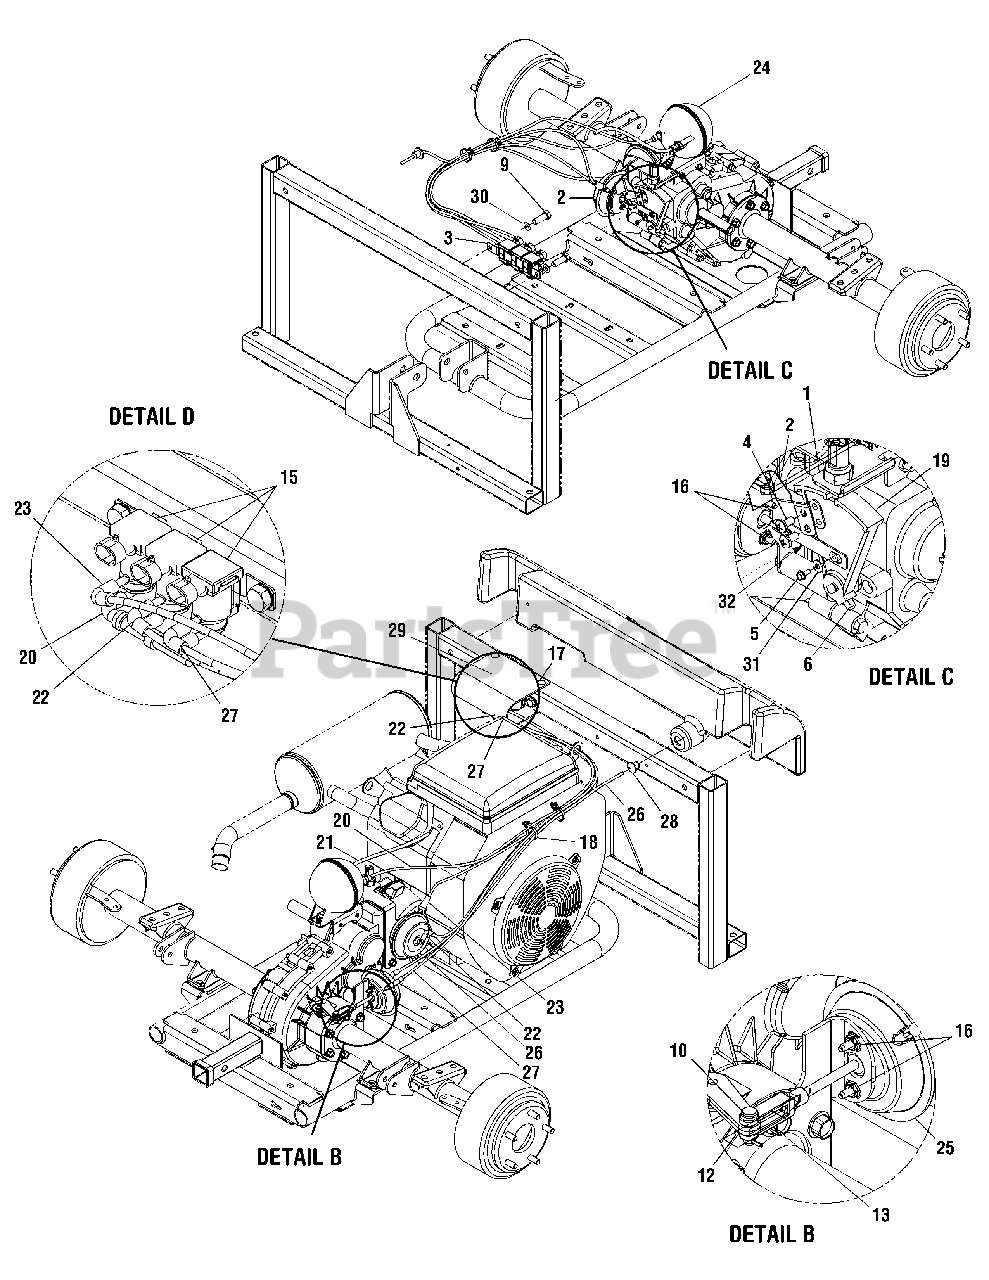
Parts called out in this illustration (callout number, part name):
1	Mounting Bracket, Vacuum Actuator
2	Bracket, Shift
3	Bracket, Vac Relay
4	Screw, 1/4-20 x.5
5	Screw, Hex. #8 - 18 .375
6	Screw, Set, 5/16-24 x .50 LG
7	Screw, 5/16-18
8	Screw, 1/4-14
9	Screw, 5/16-18 x .75 Hex
10	Pin, Yoke 1/4
11	Nut, Hex 9/16-18
12	Pin, Cotter 1/16x.750
13	Yoke, 1/4-28
14	Switch, Neutral
15	Solenoid, Kit Vacuum Actuator
16	Self Threading Nut
17	Clip, Panel Retainer
18	Cable Tie
19	Arm, Shift
21	Hose, Manifold Vacuum
22	Hose, Actuator Vacuum
23	Hose, Actuator Vacuum
24	Reservoir, Air
25	Actuator, Vac Differential Lock
26	Hose, Vac Differential Lock, Vent
27	Hose, Vac Differential Lock Supply
28	Grommet, .58 x .25
29	Cover, Solenoid
30	Flat Washer, .330 x .687 x .030
31	Flat, Washer, .188 x .437 x .042
32	Actuator, Vacuum Shift
